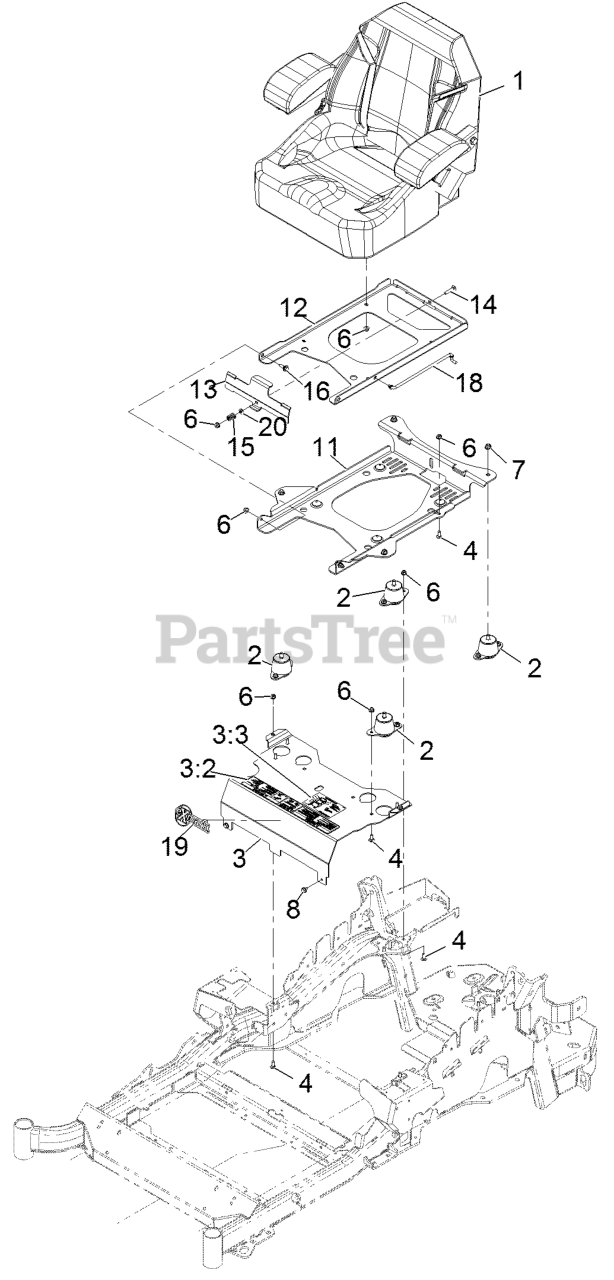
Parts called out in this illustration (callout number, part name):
2	ISOLATOR-SEAT
3	MOUNT-SEAT
3:2	DECAL-CONSOLE
3:3	DECAL-SERVICE AID
4	SCREW-CARR
6	NUT-HF, NI
7	NUT-HF, NI
11	PLATE-TILT, SEAT SUPPORT
12	PLATE-FRAME, SEAT
13	PLATE-LATCH, SEAT
14	BOLT-CARR
15	SPRING-COMPRESSION
16	SCREW-SHOULDER
18	ROD-PROP
20	WASHER-PLAIN
